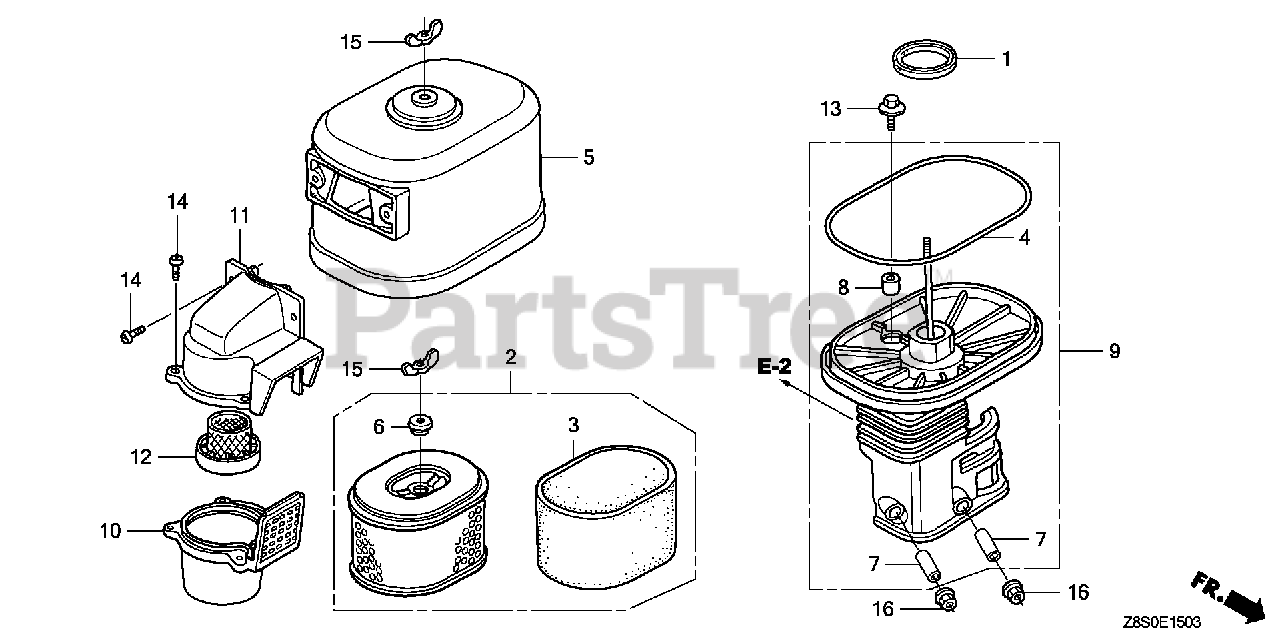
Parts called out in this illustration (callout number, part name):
1	GASKET, ELBOW
2	ELEMENT, AIR CLEANER
3	FILTER (OUTER)
4	SEAL, AIR CLEANER COVER
5	COVER, AIR CLEANER (CYCLONE)
6	GROMMET, AIR CLEANER
7	COLLAR, AIR CLEANER
8	COLLAR B, AIR CLEANER
9	ELBOW, AIR CLEANER
10	CASE, PRE AIR CLEANER
11	CAP, PRE AIR CLEANER
12	GUIDE, PRE AIR CLEANER
13	BOLT-WASHER (6X22)
14	SCREW, PAN (5X16.5)
15	NUT, TOOL BOX SETTING
16	NUT, FLANGE (6MM)
